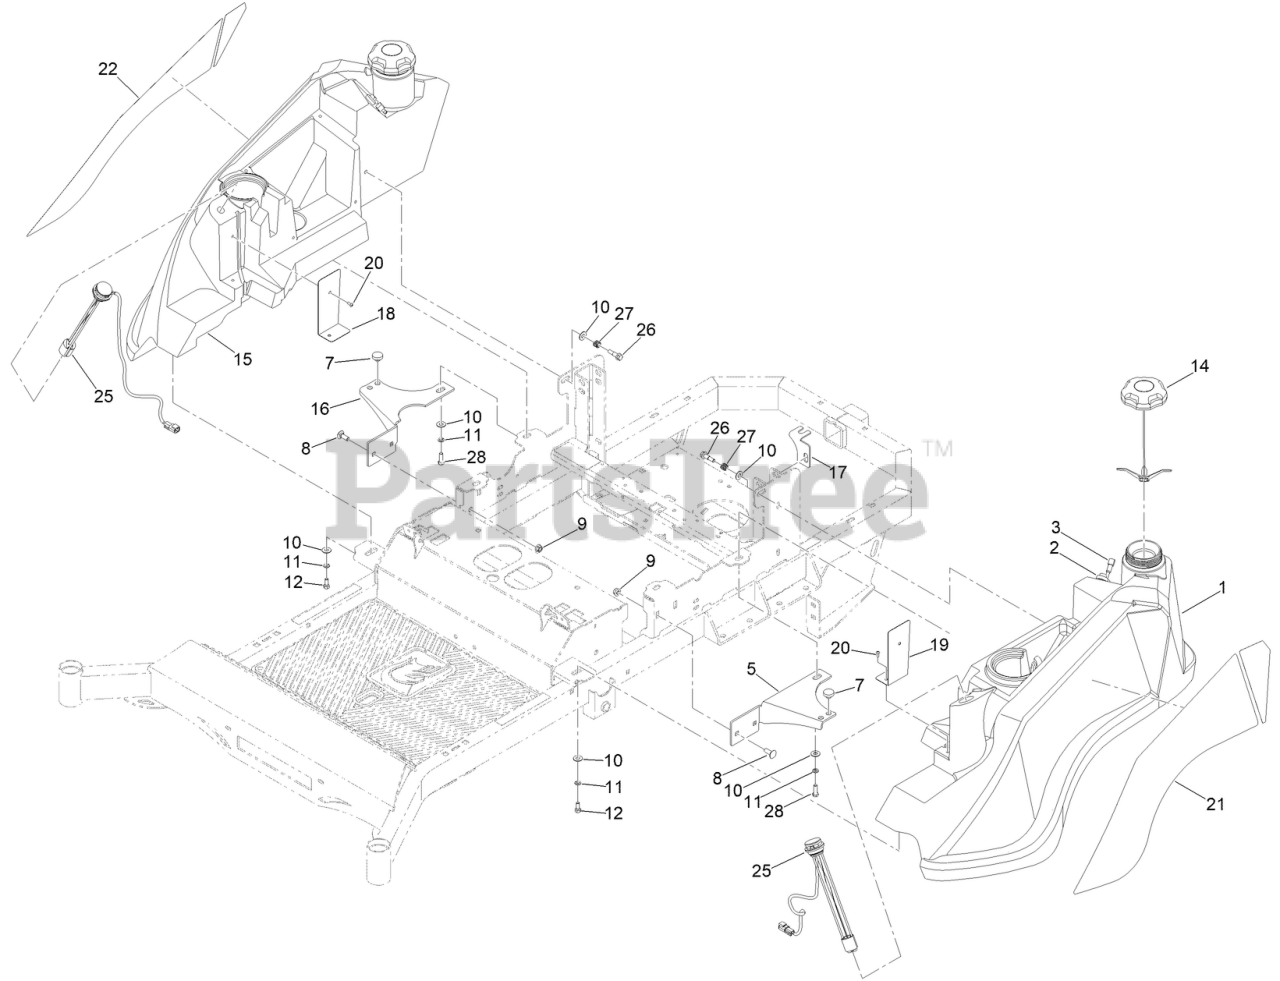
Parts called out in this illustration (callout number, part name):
1	KGZ-XD LT TANK ASSY
2	REMOTE TANK VENT VALVE W/GROMMET
3	KGZ-XD PICK UP TUBE
5	SUPPORT-TANK PAINTED BLACK
7	PUSH-IN RUBBER BUMPER MWR FLOOR
8	3/8-16 X 1 CARRIAGE BOLT YZ GR.8
9	3/8-16 HEX FLANGE NUT W/SERR ZINC YELLOW
10	WASHER-FLAT
11	WASHER-LOCK
12	SCREW-HH
14	KELCH TANK FILL NECK NON-VENTCAP(204541)
15	TANK W/ CUPHOLDER
16	SUPPORT-TANK [BLK-TXT]
17	KGZ FUEL SELECT/SHUTOFF VLV BRKT PAINT
18	KGZ FUEL GAUGE WIRE COVER RT BLACK
19	KGZ FUEL GAUGE WIRE COVER LT BLACK
20	10-24 X 1/2 BUTTON SOCKET BLACK
21	DECAL-TANK
22	DECAL-TANK
25	KGZ-XD FUEL GAUGE
26	SCREW-SHOULDER,HHF
27	SPRING-COMPRESSION
28	SCREW-HH
